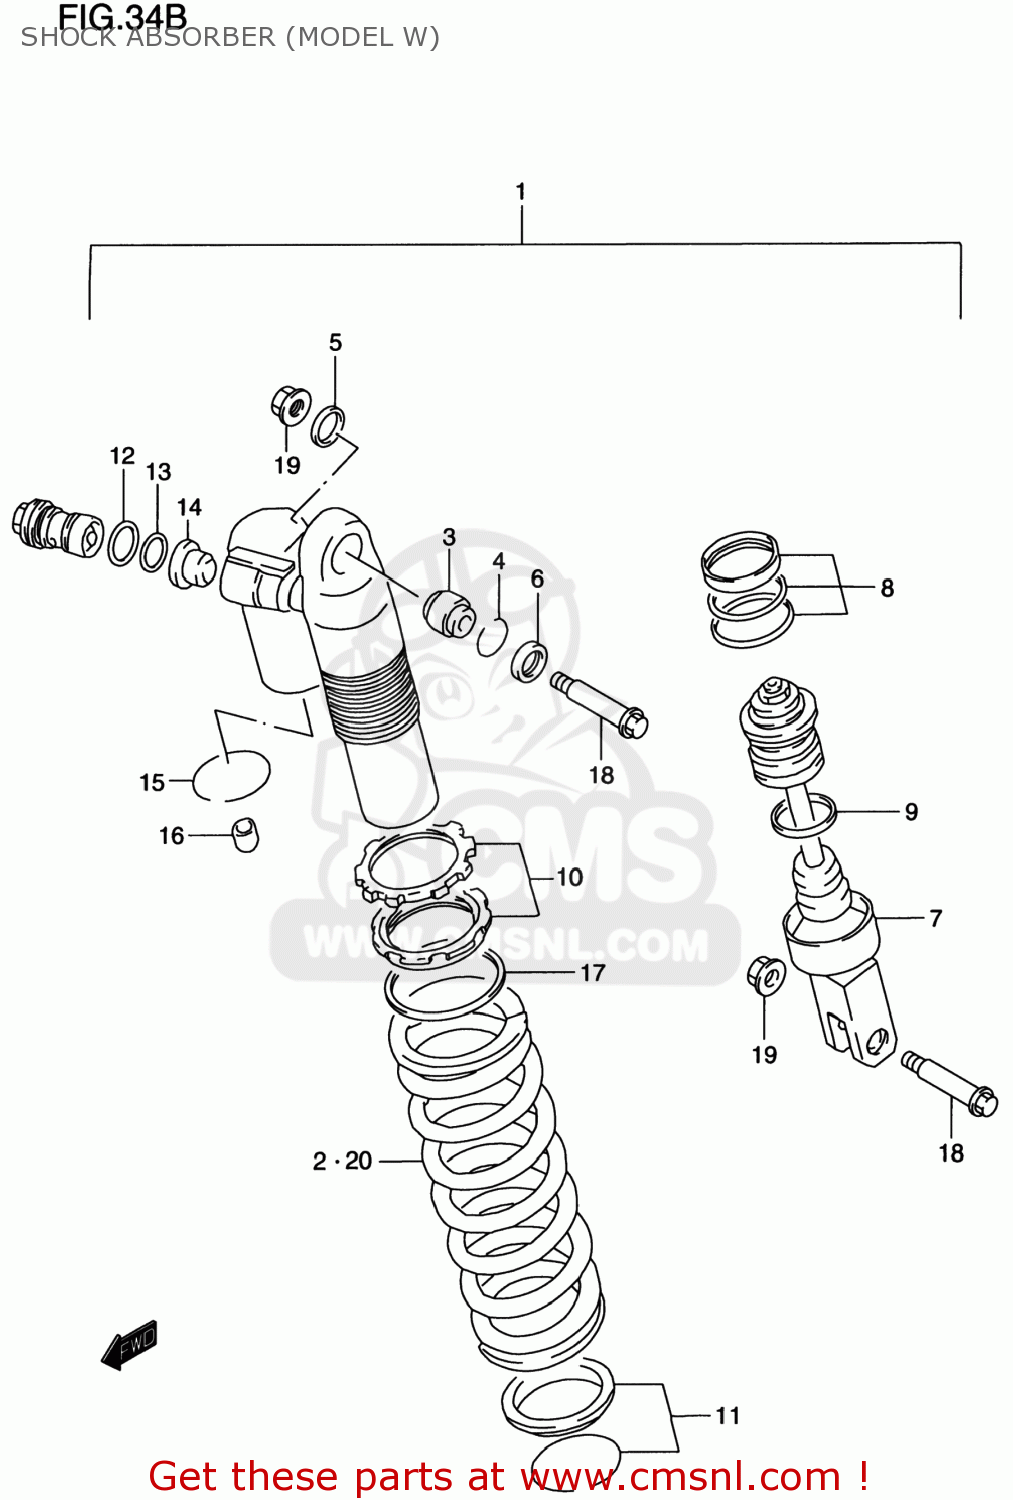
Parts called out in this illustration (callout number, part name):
1	ABSORBER ASSEMBLY,REAR SHOCK
2	SPRING,REAR (K=4.7)
3	BEARING,RR SHOCK ABSORBER
4	RING,STOPPER
5	SEAL,DUST UPR,R
6	SEAL,DUST UPR,L
7	ROD,PISTON
8	O RING SET
9	RING,STOPPER
10	ADJUSTER SET
11	SPRING SEAT SET
12	O RING
13	O RING,CTR BOLT UPR
14	COLLAR,ORIFICE
15	RING,STOPPER
16	CAP
17	SEAT,SPRING
18	BOLT(10X47.5)
19	NUT
20	SPRING,REAR (K=4.5)
